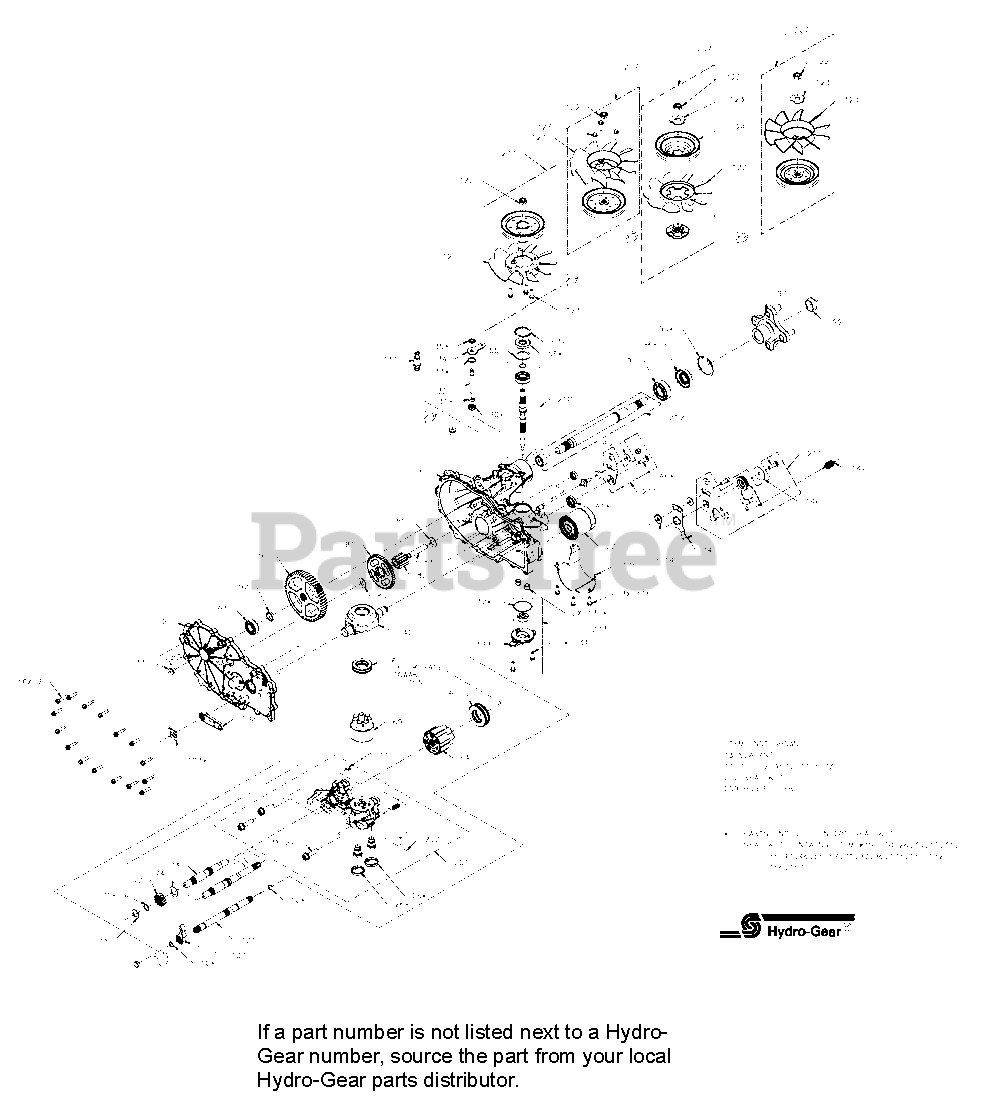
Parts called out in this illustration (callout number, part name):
1	KIT, HOUSING, MAIN, RH, CHRG, CNTL
2	KIT, COVER, SIDE, RH
7	HFHCS 1/4-20 x 1.125"
10	O-RING - 111 .103 x .424
11	PLUG 9/16-18 (METAL)
13	SEALANT
14	OIL, 20W50
22	PLATE, BYPASS
23	FILTER, OIL
26	SEAL, PLUG 1.250 x .250
27	HFHCS 3/8-16 x 1.5 (PATCH)
30	SEAL, LIP .375 x .75 x .25
31	RING, RET .375 EXTRNL
32	ROD, BYPASS
33	RING, RET .750 INTRNL
34	ARM, BYPASS
35	RING, RTNG .375 EXT
40	TRUNNION, SWASHPLATE
41	SEAL, LIP 12 x 32 x 7
45	WASHER .34 x .88 x .06
46	TWHCS 5/16-24 x 1.00 (PATCH)
55	WASHER 1.23 x 1.56 x .04
56	SEAL, LIP 17 x 40 x 7
57	RING, RETAINING
60	BEARING, THRUST
64	ASS'Y, CYLINDER BLOCK, 16cc
65	BRG, THRUST BALL 30 x 52 x 13
69	ASS'Y, BLOCK 7 PISTON
70	WASHER .63 x 1.0 x .05
71	RING, RETAINING_.625
72	GEAR, 16T
73	SHAFT, MOTOR
74	WASHER .72 x 1.16 x .04
80	WASHER .5 x 1.0 x .03
81	GEAR, 43T
82	GEAR, 11T
83	JACK SHAFT (PIN)
90	RING, RET 2.06 INT
91	GEAR, 54T
92	SPACER, .75 x 1.32 x .257
93	BEARING, BALL, .75 x 40 x 12
95	BRG, BALL 1.0 x 52 x 15 OPEN 6205M
96	SEAL, LIP 25 x 52 x 10 TC (GRAY)
97	KIT, HUB, 4 BOLT
99	NUT, HEX LOCK 3/4-16
100	PAWL, BRAKE
101	SHAFT, BRAKE
102	HANDLE, ACTUATING
103	CLIP, RETAINING
105	HFHCS 1/4-20 x .75
106	GUARD, FILTER, RH
111	FITTING, STR 9/16-18 SAE .5 BARB
120	FAN 7", 10 BLADE
122	NUT, HEX JAM 1/2-20 W/PATCH
123	HFHCS 1/4-20 x .875
130	TUBE, CONNECTING
131	GEROTOR ASSEMBLY (1.9 cc/rev)
132	O-RING, -137, 0.103 x 2.050
133	COVER, CHARGE PUMP
134	HFHCS 1/4-20 x .75
140	SPACER .320 x 1.005 x .179
141	ARM, NEUTRAL RIGHT
142	SHCS 5/16-24 x 1 PATCH
146	WASHER, .343 x 1.500 x .062
147	SPRING, EXTNSN RTN-34LBS
200	KIT, SEAL
201	KIT, CENTER SECTION, RH, CHRG
202	KIT, CHARGE RELIEF
203	KIT, CHARGE PUMP
207	KIT, FAN & PULLEY
209	UB PULLER, 4 BOLT
210	KIT, INPUT SHAFT
211	KIT, RTN, CW
212	KIT, SHAFT, AXLE
